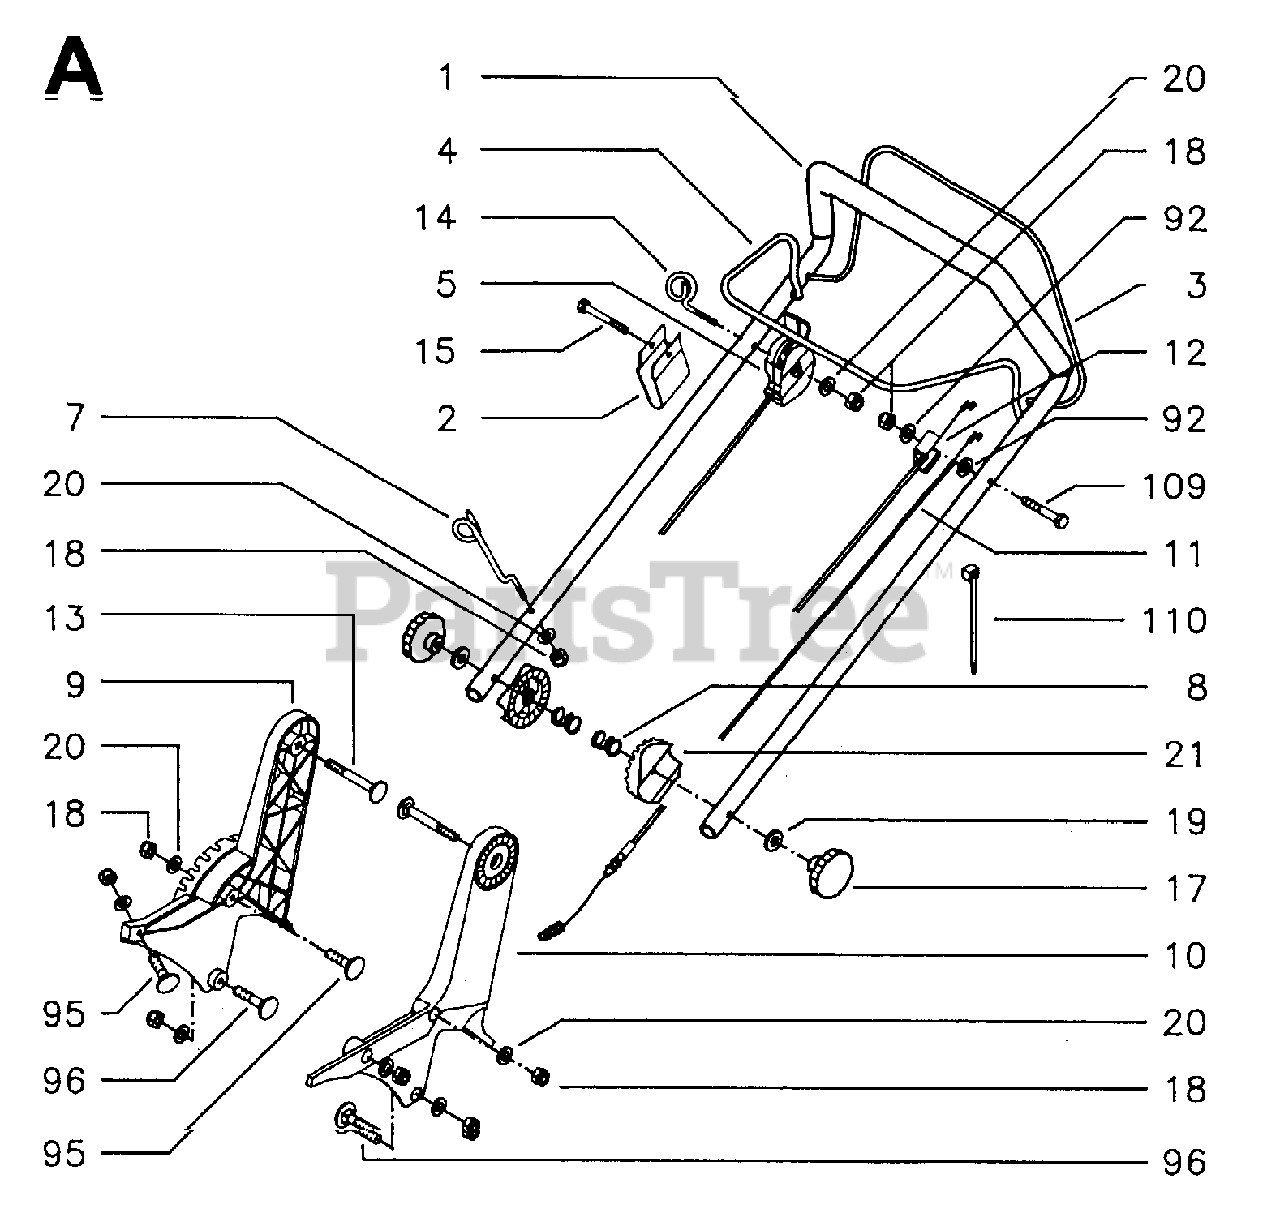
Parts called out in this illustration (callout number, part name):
5	CONTROL
17	STEERING WHEEL
18	LOCKNUT M6
95	REPL BY 515 71 16-20
